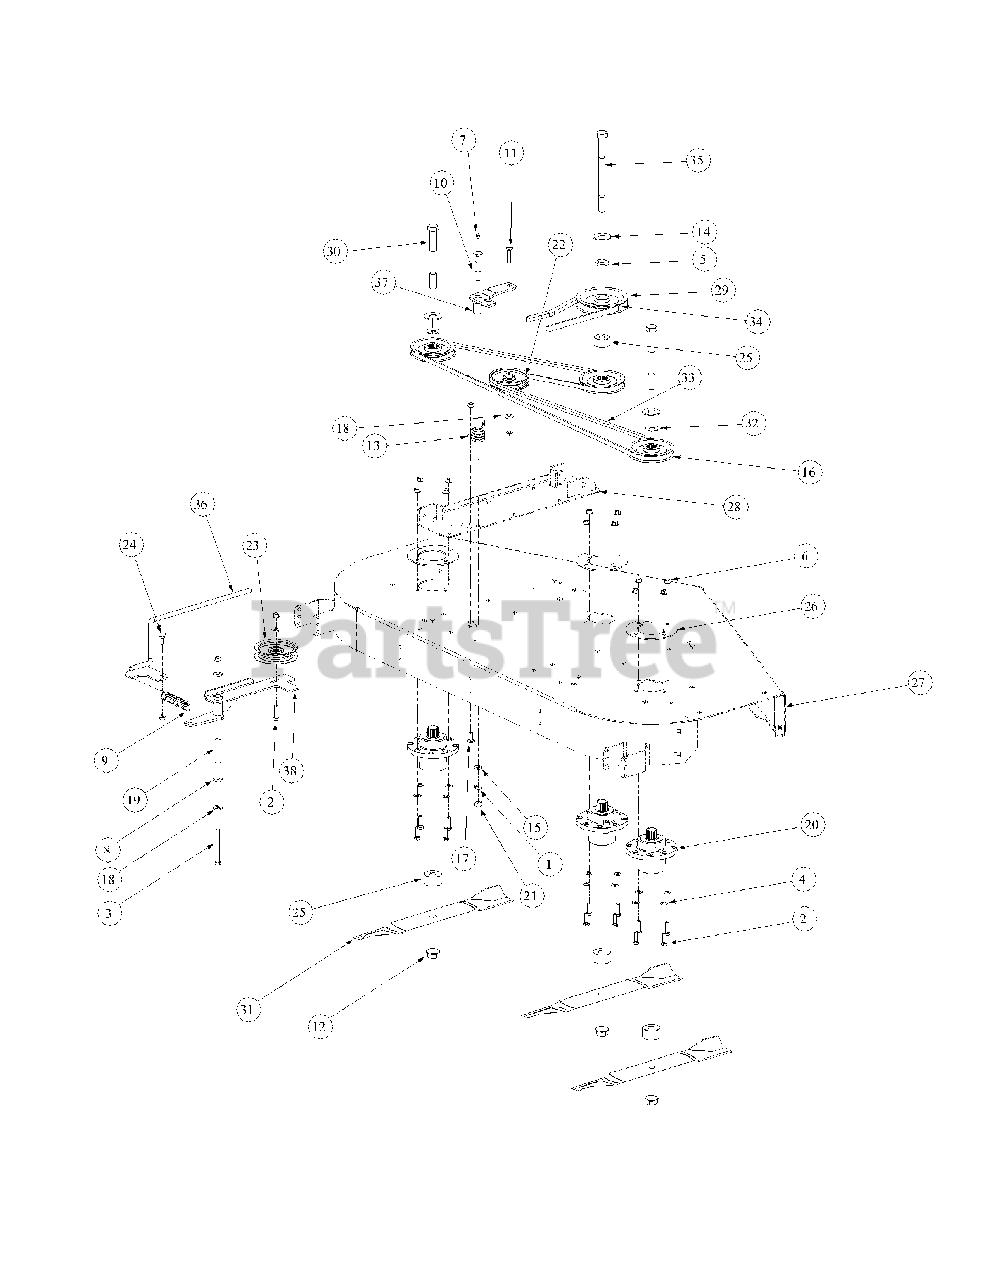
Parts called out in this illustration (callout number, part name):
1	Lock Washer, 7/16
2	Hex Cap Screw, 3/8-16 x 1-1/2
3	Hex Cap Screw, 3/8-16, 3.75
4	Flat Washer, 3/8
5	Caster Spacer
6	Flange Lock Hex Nut, 3/8-16
7	Grease Fitting, 1/4-28 x 3/16
8	Idler Washer
9	Extension Spring, 1.0 x OD x 5.125
10	Shoulder Screw, 7/16-14
11	Hex Carriage Screw, 3/8-16, 1.75
12	Flange Hex Nut, 3/4-16
13	Torsion Idler Spring
14	Flat Washer, .781 ID 2.00 OD, .105
15	Flat Washer, .469 ID, .875 OD, .105
16	V-Pulley, 4.65 OD
17	Carriage Bolt, 3/8-16 x 1
18	Flat Washer, .406 ID, 1.0 OD, .105
19	Spacer, .39 ID x .625 OD x 2.75
20	Aluminum Spindle Assembly
21	Hex Nut, 7/16-14
22	Flat Pulley
23	Idler Pulley, 4.06 OD
24	Shoulder Screw, .50 x .27 Lg., 3/8-16
25	Spacer, .760 ID x 2.00 OD x 1.1
26	Aluminum Spindle Support Plate
27	60 Deck Assembly
28	Left Hand Mount Deck Bracket Assembly
29	V-Pulley, 5.774 OD
30	Hex Cap Screw, 3/4-16, 7.00
31	Hi-Lift Blade, 21.0, 0.756 ID
32	Spacer .812 ID x .268 LG
33	V-Belt, A Section x 122.3
34	V-Belt, B Section x 91.2
35	Hex Cap Screw, 3/4-16, 9.00
36	Spring Tension Rod Assembly
37	Idler Arm Assembly, Deck Spindle
37	Bearing Sleeve
38	Idler Arm Assembly, Flat Top Bearing
38	Bearing Sleeve
